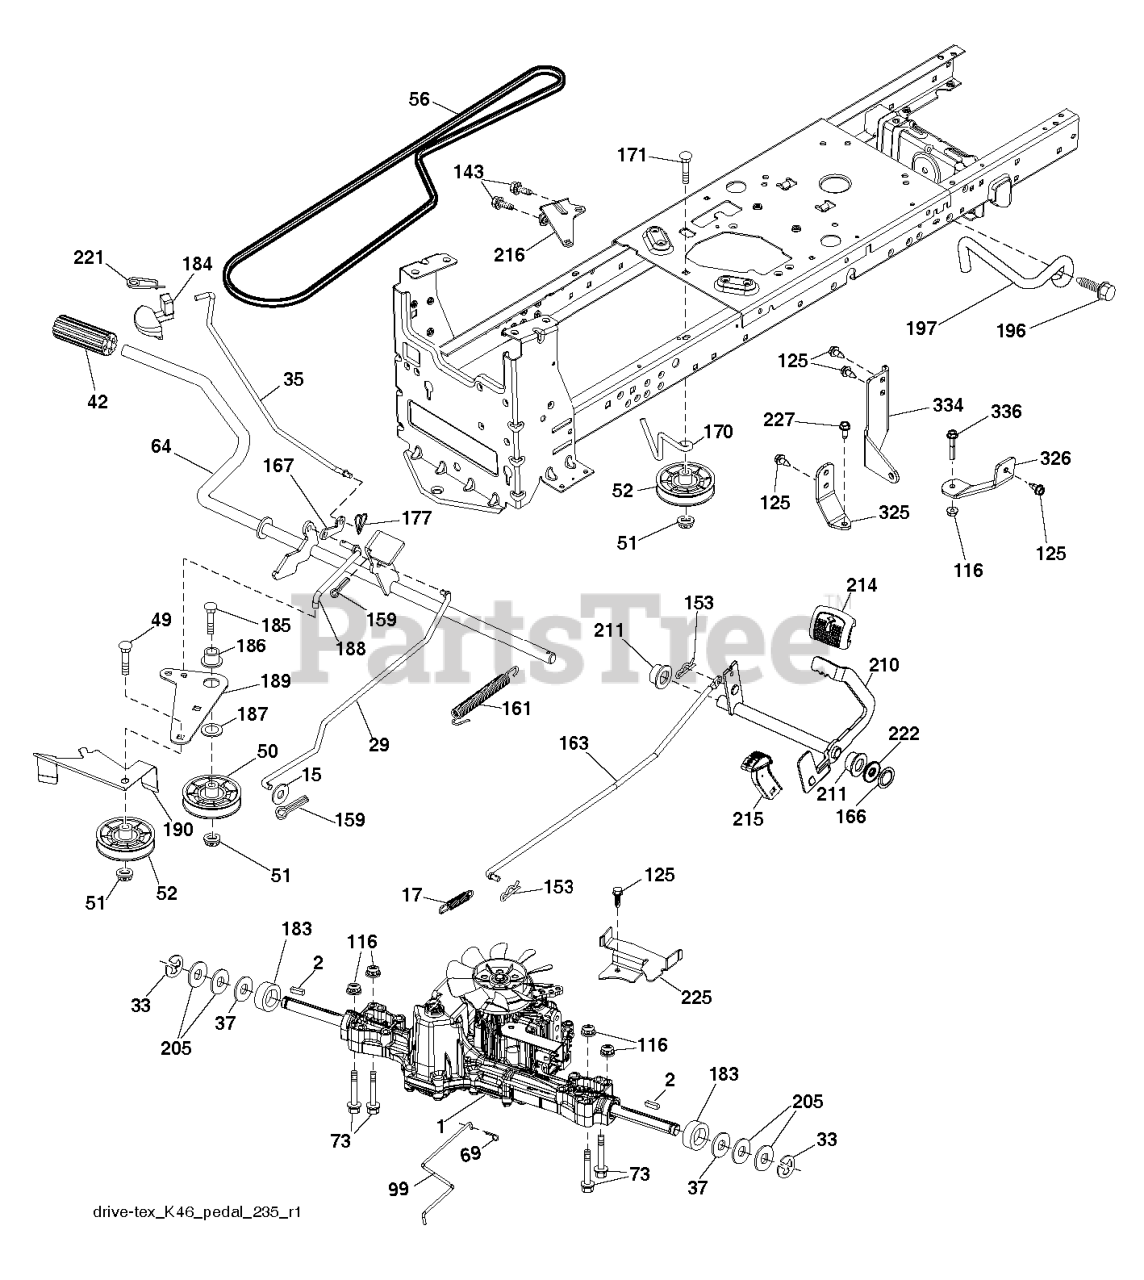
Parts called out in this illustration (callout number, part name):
1	TRANSAXLE(K46BT).PDL.
2	SQUARE KEY
15	WASHER PLAIN WASHER 3/8 X 0.08
17	SPRING.BRAKE.K46.GREEN
29	ROD.BRAKE.K46
37	WASHER.HARDENED
42	PEDAL COVER
50	IDLER.FLAT.910.OFFSET
51	NUT LOCK FLG 3/8-16 UNC
52	IDLER.V-GROOVE.910.OFFSET
64	SHAFT.ASM.PEDAL.BRK.CNTR
69	HAIRPIN.SOFT.ZINC.059X1.125
99	ARM.PIVOTING.TCRD.GEN2.5.BAGGE
125	SCREW
153	RETAINER M
161	SPRING, RETURN LT
166	NUT.PUSH.625
167	LATCH.BRAKE.SPRING
170	KEEPER.V-IDLER.CENTER.
177	PIN COTTER;LOCKING;BOWTIE;1IN
183	SPACER AXLE
184	HANDLE.PARKING.BRAKE.H (BLK)
186	SPACER.RETAINER
188	LINK.CLUTCH.GROUND DRIVE.LONG
189	BELLCRANK.GROUND.DRIVE.TEX.
190	KEEPER.BELLCRANK.DRIVE
196	SCREW 3/8-16X1
210	ROCKER.ASM.PEDAL.CONTR
211	BEARING.NYLON
214	PEDAL.FORWARD.PAD.TEX
215	PEDAL.COVER.REVERSE.CRD.X428BK
216	BRACKET.PULLEY.IDLER.W/TEX
221	RETAINER.SPRING.CLIP.H
222	WASHER 21/32 X 1-1/4 X 10 GA.
225	KEEPER.BELT.TRANSAXLE.K46
325	BRACKET.TRQ.STP.46.20".TIRE.LH
326	BRCKT.PNT.TRQ.STP.46.20TIRE.RH
334	SWAY.ROD.BRACKET.K46.X431
